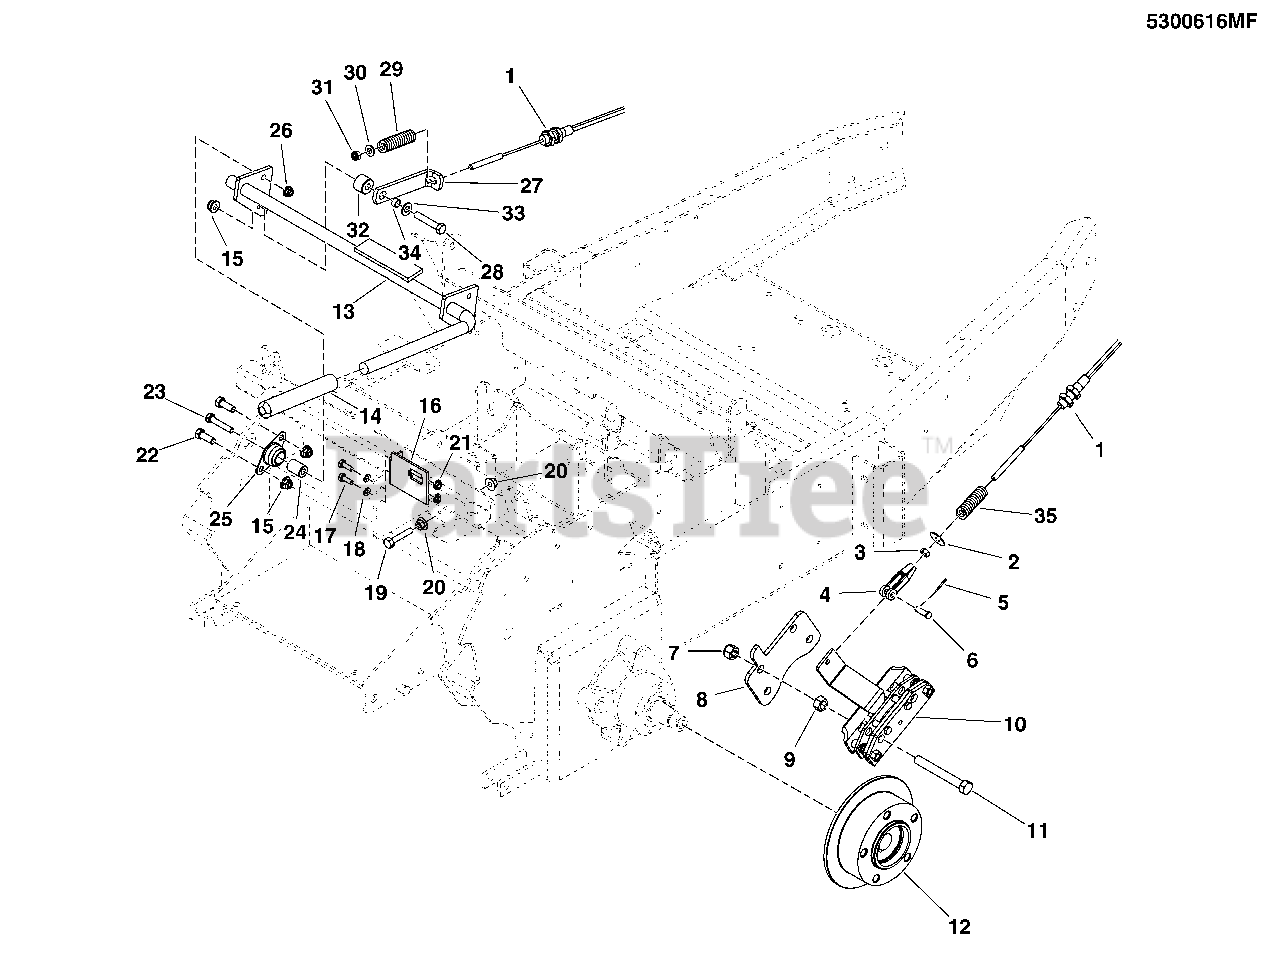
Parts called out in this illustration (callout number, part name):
1	CABLE, PARKING BRAKE IS2000
2	WASHER, 5/16 FENDER
3	NUT, 5/16-24 HEX
4	CLEVIS, 5/16-24, STEEL, CLEAR ZINC
5	PIN, COTTER, 3/32 X 3/4
6	PIN-CLEVIS, 5/16 X 1 YZ
7	NUT, 1/2-13 HEX NYLON LOCK
8	MOUNT, BRAKE CALIPER - RED
9	NUT, 1/2-13 HEX
10	COMPACT CALIPER, AUSCO (86978)
11	BOLT, 1/2-13 X 4 GD5 YZ
12	WHEEL HUB, COMPACT CALIPER (86720)
13	WELD, BRAKE SHAFT - RED
14	GRIP, FOAM, 3/4 ID X 6 X .187
15	NUT, 3/8-16 HEX NYLOCK FLANGE
16	BRACKET, SWITCH MOUNT - RED
17	BOLT, 1/4-20 X 3/4 GD5 YZ
18	WASHER, 1/4 SAE
19	BOLT- 5/16-18 X 1-3/4 GD5 TFL
20	NUT, 5/16-18 HEX SERRATED FLANGE (LARGE)
21	NUT, 1/4-20 HEX SERR. FLANGE
22	BOLT, 3/8-16 X 1 GD5 YZ
23	BOLT, 5/16-18 X 1-3/4 GD5 YZ
24	SPACER, .32 X .75 X 1.06
25	BEARING, BRONZE FLANGE, 3/4
26	NUT, 5/16-18 HEX NYLOCK FLANGE
27	LINK, BRAKE LOCK - BLK
28	BOLT, 3/8-16 X 2 GD5 YZ
29	SPRING-COMP, .75 X .162 X 2.5
30	WASHER, 5/16 SAE
31	NUT, 5/16-24 HEX NYLON LOCK
32	SPACER, .39 X 1.00 X .75
33	WASHER, 3/8 SAE
34	SPACER, .38 X .50 X .27
35	SPRING, COMPRESSION, 5-1/2
